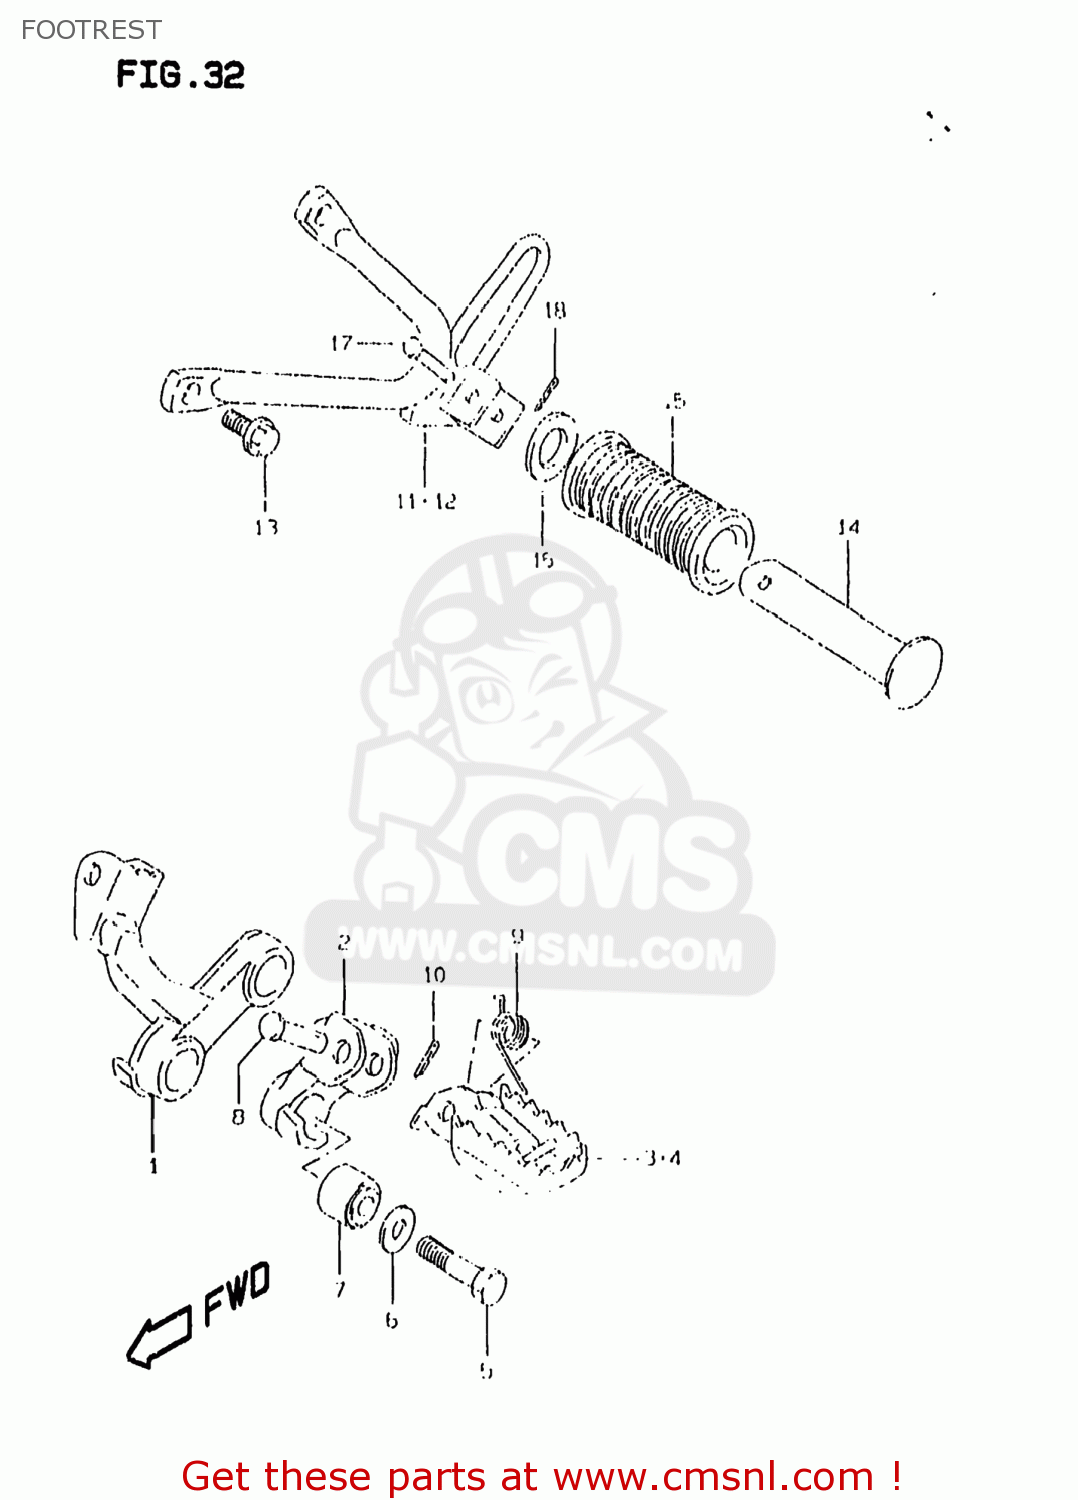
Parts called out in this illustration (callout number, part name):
1	BRACKET,FR FOOTREST,R
2	BRACKET,FR FOOTREST,L
3	FOOTREST COMP,FRONT,RIGHT
4	FOOTREST,FR,L
5	BOLT(10X45)
6	WASHER(10.5X22X1.6)
7	BUSH(10.2X25X19)
8	PIN
9	SPRING
10	PIN
11	BRACKET,PILLION FOOT,R(BLACK)
12	BRACKET,PILLION FOOT,L(BLACK)
13	BOLT
14	BAR,FOOTREST RUBBER
15	RUBBER,PILLION FOOTREST
16	WASHER(19.5X32X2)
17	PIN
18	PIN
